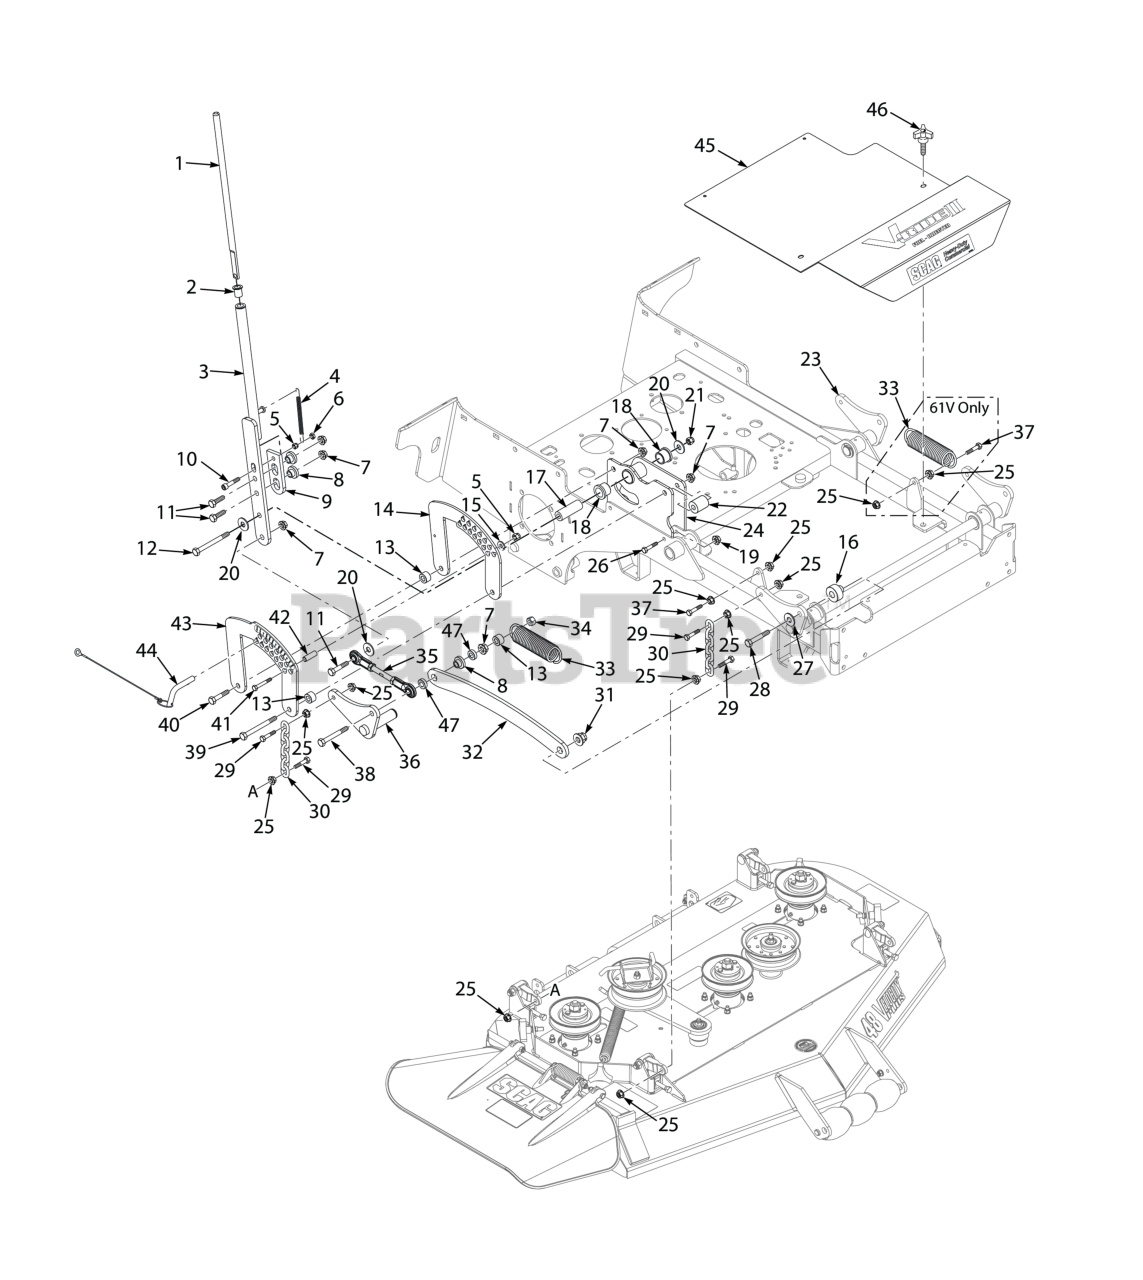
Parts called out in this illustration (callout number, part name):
1	Actuator Rod, Deck Latch
2	Bearing, .625 ID Plastic
3	Handle Weldment, Deck Latch
4	Spring, Deck Latch
5	HEX NUT, ELASTIC STOP LOCK, 3/8-16
6	Bolt, Hex Head 3/8-16 x 1" Ser. Flg.
7	Nut, Hex Serrated Flange 1/2-13
8	Bushing, Deck Lift
9	Deck Latch, Outer
10	Capscrew, Socket Head 3/8-16 x 1-3/4"
11	Bolt, Hex Head 1/2-13 x 1-3/4"
12	Bolt, Hex Head 1/2-13 x 4-1/4"
13	Spacer
14	Bracket, Deck Height
15	Flatwasher, 3/8" Special (.391 x .938 x .105)
16	Bushing, Deck Lift
17	Sleeve, Brake Pivot
18	Bearing, Plastic
19	Nut, Flange Elastic Stop Nut, 3/8-16
20	Flat Washer, 1/2 (.562 x 1.375 x .109)
21	HEX LOCKNUT, ELASTIC STOP, 1/2-13
22	Spacer, Decklift Pivot
23	Arm Weldment, LH
24	Deck Lift Pivot Assy.
25	NUT, 3/8-16 SERRATED FLANGE HEX HEAD
26	Bolt, Hex Head, 3/8-16 x 1 Gr. 5
27	Washer, Flat, 1/2-.562 x 1.375 x .109 HD
28	Bolt, Hex Hd. 1/2-13 x 2-1/2" (lower)
29	Bolt, Hex Head 3/8-16 x 1-1/2" B&S 32BV
30	CHAIN ASSY
31	Nut, Elastic Stop 1/2-13, (STT-52 & STTII-52)
32	Link, Deck Lift
33	Spring, Deck Lift
34	Locknut, Hex 1/2-13 Center Lock
35	Link, Deck Lift
36	Arm Weldment, RH
37	Bolt, Hex Head 3/8-16 x 1-1/2" Grade 8 Black
38	Bolt, Hex Head 1/2-13 x 3-1/2"
39	Bolt, Hex Head 1/2-13 x 4" (lower)
40	Hex Head Bolt, 1/2-13 x 2"
41	Bolt, Hex Head 3/8-16 x 2-1/4" - 61"
42	Bushing, .502 O.D.
43	Bracket, Deck Height - Outer
44	Pin Assy. w/Lanyard
45	Belt Cover w/Decals
46	Knob, w/stud 3/8-16 x 1-1/4"
47	Spacer, Radiator
